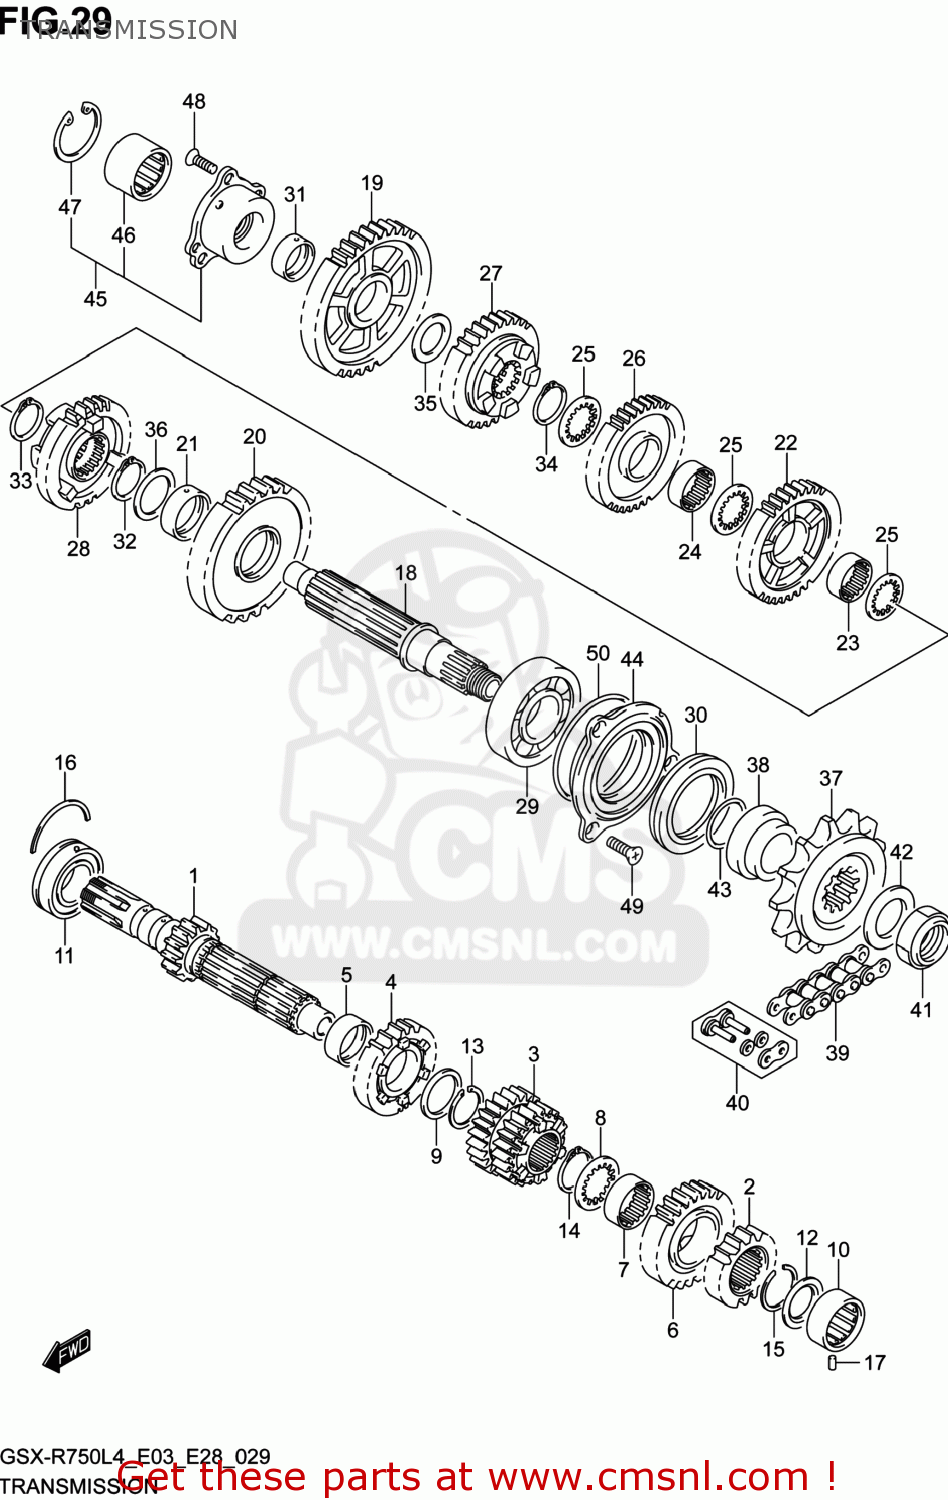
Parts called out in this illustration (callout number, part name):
1	SHAFT,COUNTER
2	GEAR,2ND DRIVE
3	GEAR,3RD & 4TH DRIVE
4	GEAR,5TH DRIVE
5	BUSH,5TH DRIVE GEAR
6	GEAR,6TH DRIVEN(NT:24)
7	BUSH,6TH DRIVE GEAR
8	WASHER,LOCK
9	WASHER(27X36X1)
10	BEARING(20X34X13.5)
11	BEARING(25X62X17)
12	SEAL,OIL(20X31.2X2.7)
13	CIRCLIP
14	CIRCLIP
15	CIRCLIP
16	C RING
17	PIN(6X10)
18	SHAFT,DRIVE
19	GEAR,1ST DRIVEN
20	GEAR,2ND DRIVEN(NT:39)
21	BUSH,2ND DRIVEN GEAR
22	GEAR,3RD DRIVEN
23	BUSH,3RD DRIVEN GEAR
24	BUSH,3RD DRIVEN GEAR
25	WASHER,3RD & 4TH DRIVEN
26	GEAR,4TH DRIVEN
27	GEAR,5TH DRIVEN(NT:31)
28	GEAR,6TH DRIVEN
29	BEARING(28X68X18)
30	SEAL,OIL(42X62X7)
31	BUSH(22X26X9)
32	CIRCLIP
33	CIRCLIP
34	CIRCLIP
35	SHIM(22X34X1)
36	WASHER(27X36X1)
37	SPROCKET,ENGINE(17T)
38	SPACER,ENGINE SPROCKET
39	CHAIN,DRIVE
40	JOINT SET,DRIVE CHAIN
41	NUT
42	WASHER(25X41X3)
43	O RING(D:2.4,ID:23.7)
44	RETAINER,DRIVE SHAFT BEARING,L
45	HOUSING,DRIVE SHAFT SET
46	BEARING(20X34X17.5)
47	CIRCLIP
48	SCREW(6X20)
49	SCREW(6X20)
50	O RING(D:1.8,ID:67.5)
